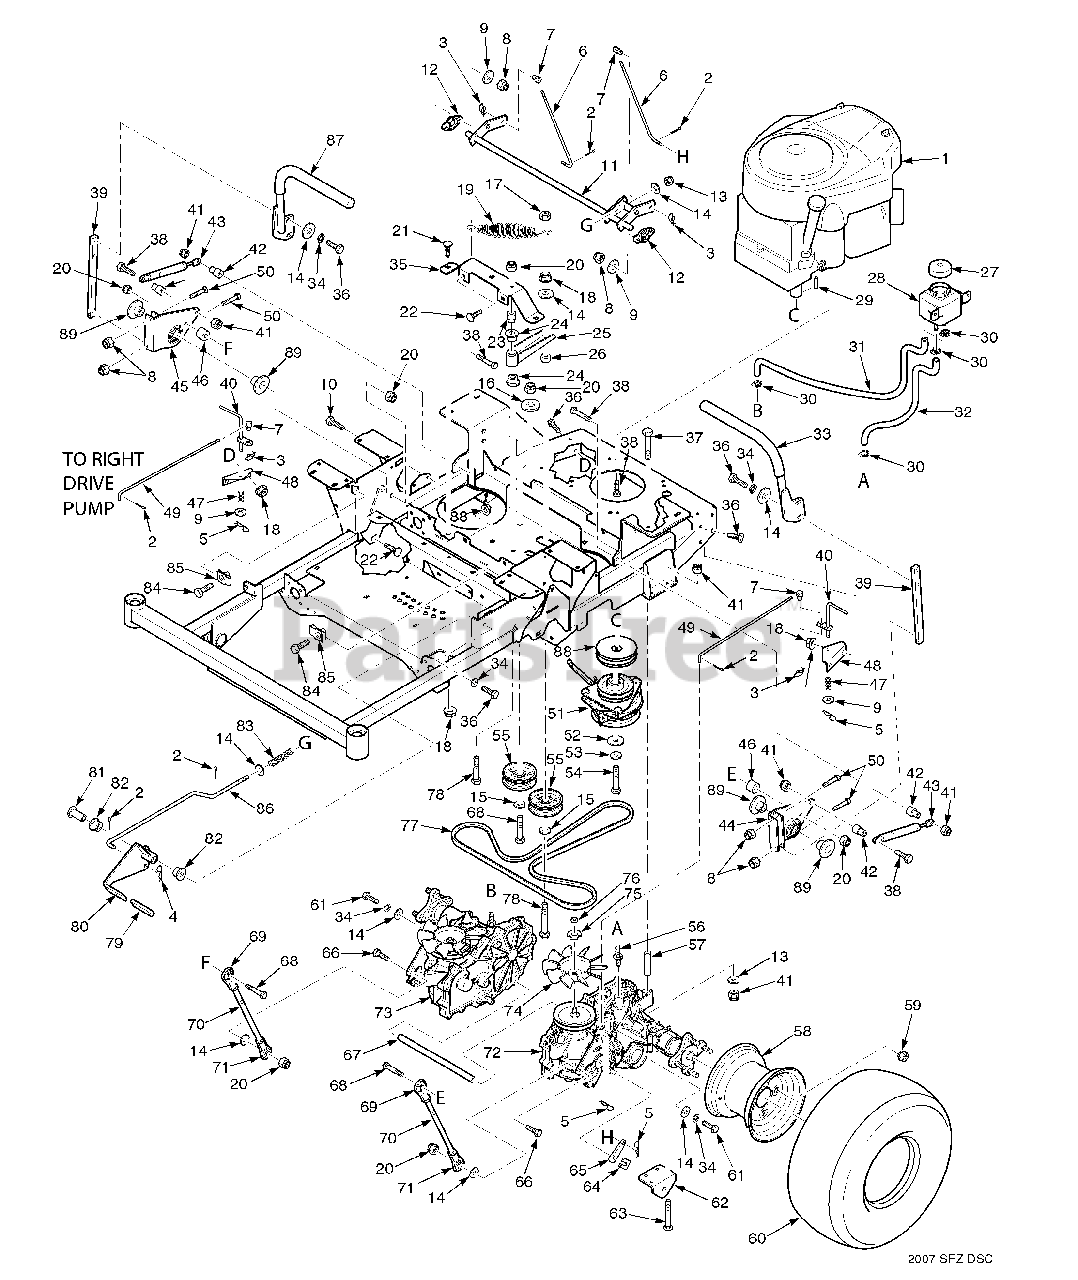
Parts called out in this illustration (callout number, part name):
2	Cotter Pin, 3/32 x 1"
3	Pin, Rue Cotter 3/8" Dia.
4	Hair Pin Cotter, .080 x 1.19"
5	Nut, Serrated Flange 5/16-18
6	Rod, Brake Adjustment
7	Joint, Swivel
8	Nut, Elastic Stop 1/4-20
9	Flatwasher, 1/4-.312 x .750 x .065
10	Bolt, Serratted Flange 1/4-20 x 1-1/4"
11	Weldment, Brake Lever
12	Bearing
13	Flatwasher, 5/16-.375 x .875 x .083
14	Flatwasher, 3/8-.391 x .938 x .105
15	Flatwasher, 3/8-.391 x .938 x .105 HD
16	Flatwasher, 3/8-.406 x 1.5 x 7 GA.
17	Nut, Center Lock 3/8-16
18	Nut, Serrated Flange 3/8-16
19	Spring, Transmission Idler
20	Nut, Elastic Stop 3/8-16
21	Bolt, Carriage 3/8-16 x 3/4"
22	Bolt, Carriage 5/16-18 x 3/4"
23	Shaft Pivot, Idler Arm
24	Bearing
25	Transmission Idler Arm Assy.
26	Spacer, Idler Pulley
28	Reservoir Assy.
29	Key, 1/4 x 1/4 x 1-3/4"
30	Clamp, .87" Max Dia.
31	Hose, RH Transmission
32	Hose, LH Transmission
33	Handle Bar Assy. w/Grip
34	Lockwasher, 3/8" Spring
35	Support, Idler Arm
36	Bolt, Hex Head 3/8-16 x 1"
37	Bolt, Hex Head 5/16-18 x 3"
38	Bolt, Hex Head 5/16-18 x 1-1/2"
39	Bar, Control Lever
40	Dump Valve Lever
41	Nut, Elastic Stop 5/16-18
42	Spacer, Pump Dampener
43	Dampener
44	Control Linkage, LH
45	Control Linkage, RH
46	Spacer
47	Spring
48	Bracket, Dump Mounting
49	Rod, Brake Linkage
50	Bolt, Hex Head 1/4-20 x 1-1/2"
51	Electric Clutch Assy.
52	Flatwasher, 7/16-.469 x 1.75 x .25
53	Lockwasher, 7/16" Spring
54	Bolt, Hex Head 7/16-20 x 2-1/4" Patch
55	Pulley, 3-1/2" Dia.
56	Fitting, Transmission
57	Spacer, Axle
58	Rim w/Valve Stem
59	Wheel Nut, 1/2-20
60	Wheel Assy.
61	Bolt, Hex Head 3/8-16 x 2-1/4"
62	Bracket, Pusharm Link
63	Bolt, Hex Head 5/16-18 x 3"
64	Clip, Brake Lever
65	Lever, Brake
66	Bolt, Hex Head 3/8-16 x 1-1/4"
67	Spacer, Axles
68	Bolt, Hex Head 3/8-16 x 2"
69	Rod End, 3/8-24 UNF RH
70	Linkage, Pump
71	Rod End, 3/8-24 UNF LH
72	Transaxle Assy, LH
73	Transaxle Assy, RH
74	Fan
75	Fan Washer
76	Fan Nut
77	Belt, Transmission Drive
78	Bolt, Hex Head 3/8-16 x 3"
79	Grip, Brake Handle
80	Brake Handle Assy.
81	Spacer, Brake Handle
82	Bearing
83	Spring, Brake
84	Bolt, Hex Head 3/8-16 x 1-1/4 Special Lock
85	U-Nut, 3/8-16
86	Rod, Brake Linkage
87	Handle Bar w/Grip
88	Pulley, 4-1/2" Dia. 1" Bore
89	Spacer, Linkage
